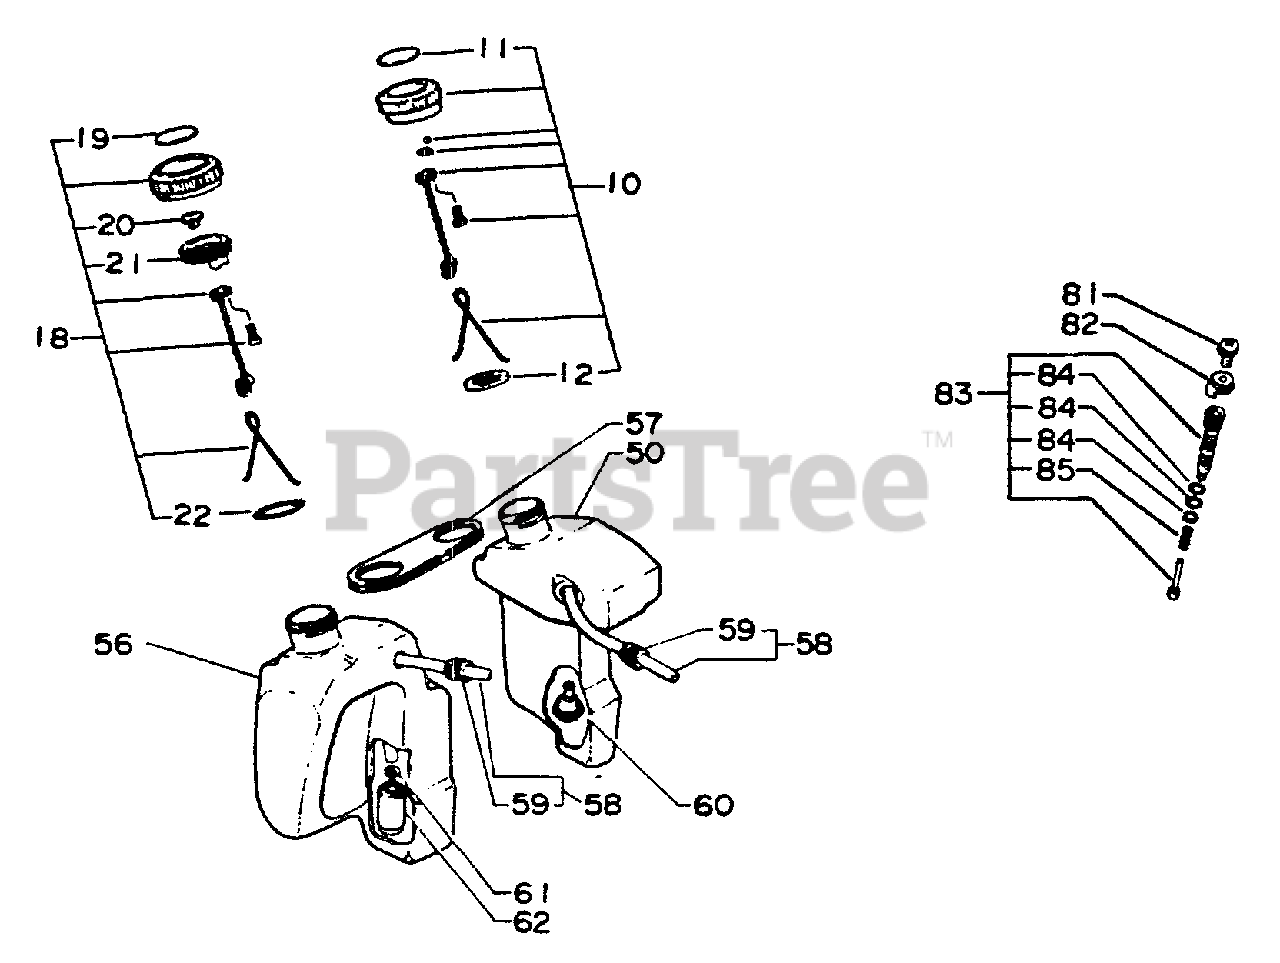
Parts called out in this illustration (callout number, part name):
10	CAP ASSY
11	LABEL - CHAIN OIL
12	GASKET, CAP
18	CAP ASSY
19	LABEL - FUEL MIX
20	VALVE, CHECK
21	HOLDER, CHECK VALVE
22	O-RING 22
50	TANK, OIL
56	TANK, FUEL
57	CONNECTOR
58	FUEL PIPE KIT
60	FILTER, OIL
61	WASHER 5.5×12×0.8
62	FILTER, FUEL
81	SCREW 5×10
82	WASHER, LOCK
83	AUTO-OILER ASSY
